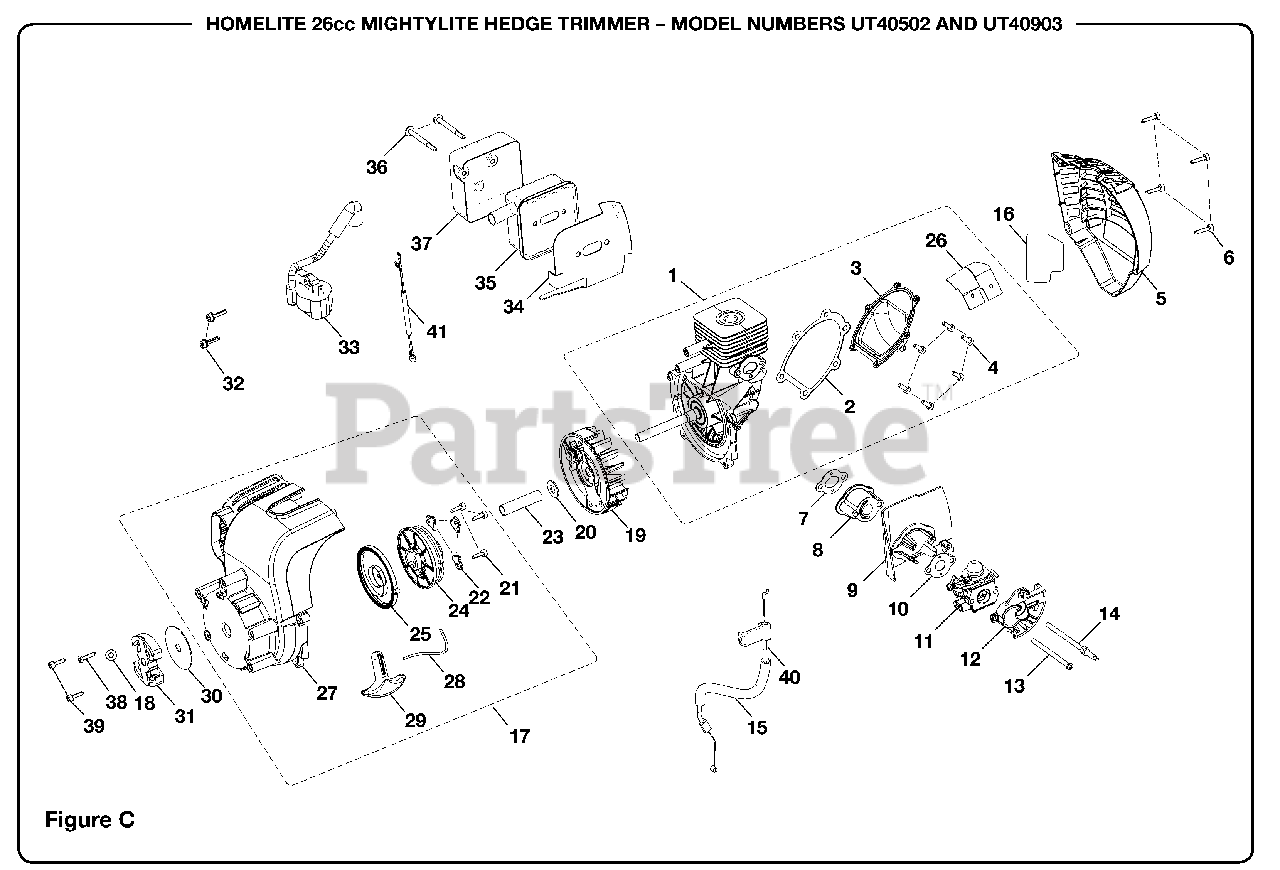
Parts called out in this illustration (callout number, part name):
1	Short Block Assembly
2	Crankcase Cover Gasket
3	Crankcase Cover
4	Screw (M4 x 12 mm)
5	Upper Housing
6	Screw (M4 x 18 mm)
7	Intake Gasket
9	Heat Dam Deflector
10	Carburetor Gasket
11	Carburetor
12	Roto-Choke Base
13	Bolt (M5 x 70 mm)
14	Double Sided Hex Bolt
16	Heat Shield Gasket
17	Front Housing Assembly
19	Flywheel Assembly
20	Washer
21	Screw (M4 x 14 mm)
22	Pulley Retainer
23	Spacer Tube
24	Starter Pulley
25	Spring & Container Assembly
26	Heat Shield (Crankcase)
27	Lower Housing Assembly
28	Starter Rope
29	Pulley Handle
31	Clutch Assembly
32	Screw (M4 x 19 mm)
33	Ignition Module
34	Muffler Gasket
35	Muffler Assembly
36	Screw (10-24 x 2-3/16 in Shoulder)
37	Heat Shield (Muffler)
38	Screw (M4 x 20 mm)
39	Screw (M4 x 16 mm)
40	Throttle Cable
41	Lead Assembly
